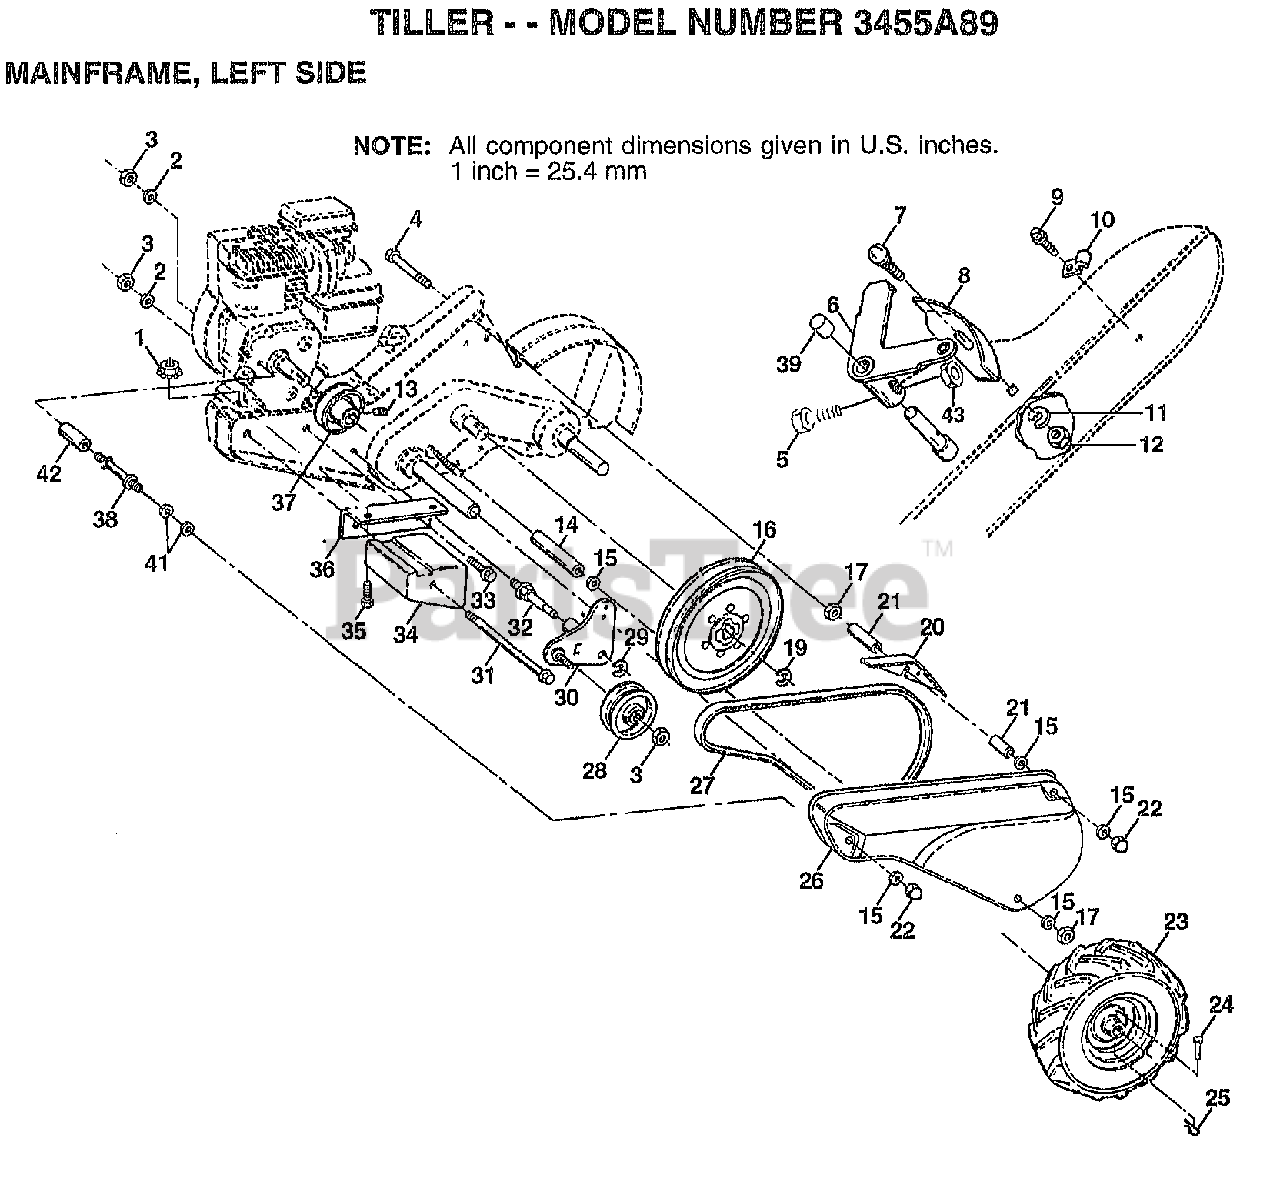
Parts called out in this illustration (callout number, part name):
2	LOCKWASHER
3	NUT.HEX.3/8-16UNC
4	BOLT TI
5	"SCREW-LEVER,SHI"
6	LEVER ASM CRT
7	BOLT
8	PANEL TI
10	CONDIUT CLIP T
11	LOCKWASHER
13	SET SCREW
14	SPACER
15	WASHER
16	SHEAVE.TRANS.
17	NUT.HEX.5/16-18
20	GUARD CRT
21	SPACER.SPLIT
22	NUT TI
23	TIRE TI
23	RIM
24	RIVET.DRILL.1.75
27	BELT-V
28	PULLEY-IDLER TI
29	KLIP RING
30	BRACKET ASM IDLER
31	BOLT CRT
32	SHIFT ARM CRT
33	BOLT
34	COUNTERWEIGHT CRT
35	BOLT.HEX.5/16-1.5
36	BRACKET LH CRT
37	ENGINE PULLEY
38	STUD.GUARD.BELT
39	CAP PLUNGER BLACK
41	WASHER
43	LOCKNUT
